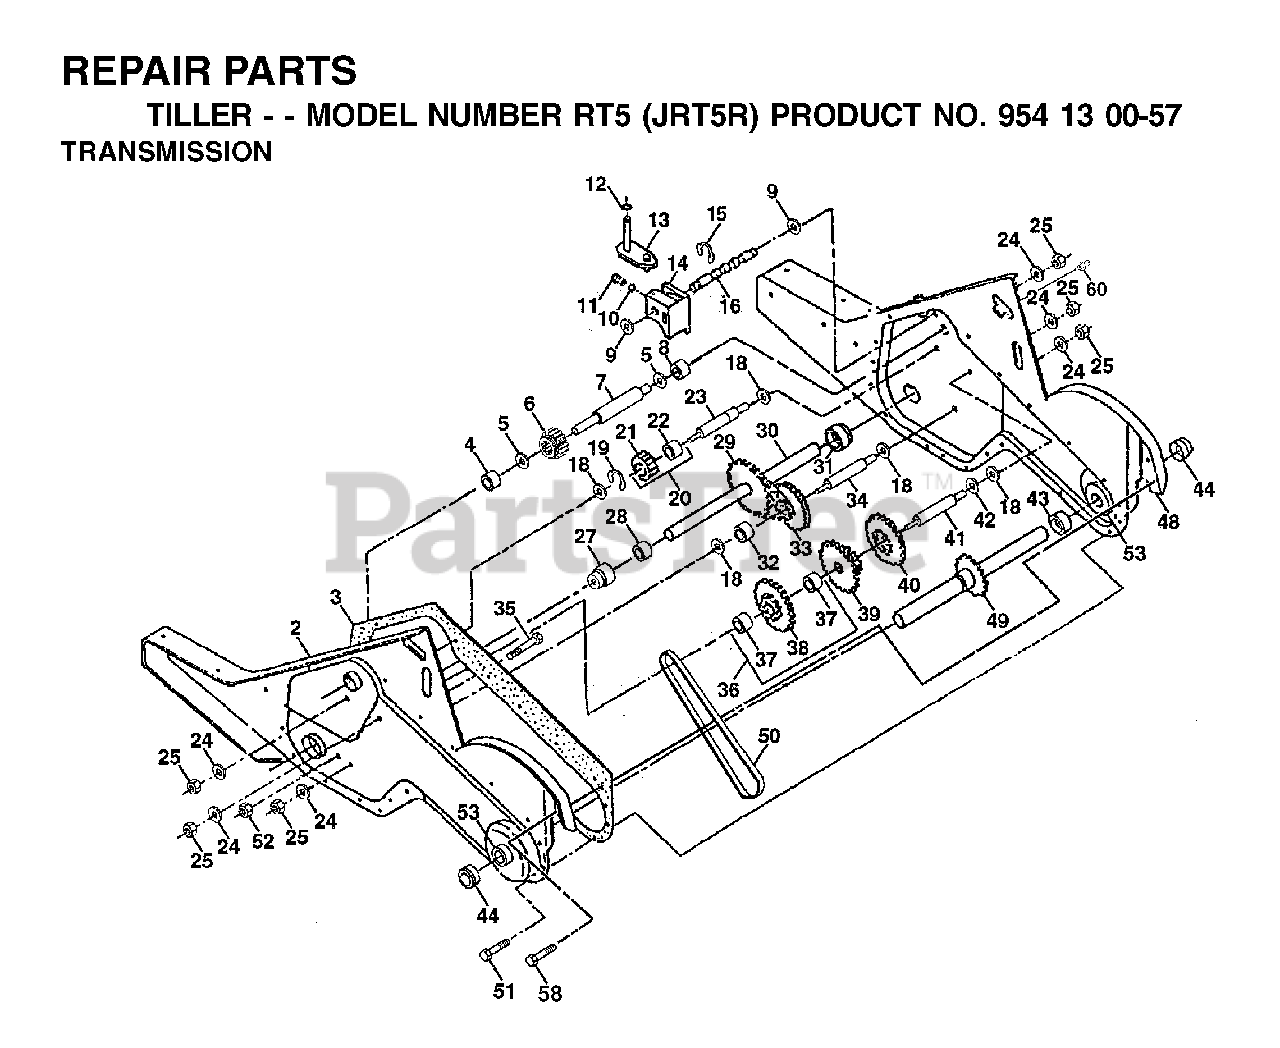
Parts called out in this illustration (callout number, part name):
1	TRANS SERV
2	GEAR CASE
3	GASKET
4	NEEDLE BRNG LT
5	THRUST WASHER
6	GEAR.PINION.INPUT
7	SHAFT.INPUT."D".TILLER
8	BEARING TI
9	WASHER, SEAL
10	STEEL BALL KIT
11	SPRING-SHIFT CRT
12	O-RING TI
13	SHIFTING ARM
14	SHIFT FORK TI
15	KLIP RING
16	SHAFT.SHIFTER.TILLER
19	KLIP RING
20	GEAR ASSY CRT
21	GEAR-REV IDLR CRT
22	NEEDLE BEARING TI
23	SHAFT CRT
24	LOCKWASHER
27	BEARING, SHAFT LH CRT
29	CHAIN CRT
30	GROUND SHAFT ASS'Y
31	BEARING, SHAFT RH CRT
32	SPACER TI
33	SPRCKT 8 GEAR CRT
34	SHAFT.SECONDARY.REDUCTION.CRT
35	SCRW WHIZ LOK CRT
36	SPROCKET ASS'Y W/BRG
37	BEARING
38	SPROCKET, TINE
39	GEAR TI
41	SHAFT.REDUCTION.TILLER
42	BRNG RACE T
43	SPACER TI
44	SEAL ASM, OIL
48	GEARCASE, R.H. W/BEARING
49	TINE SHAFT
50	CHAIN.TILLER
51	SCREW
52	NUT
53	BEARING KIT
58	BOLT SHOULDER 1/4-20 UNC X.875
60	ZERK M
